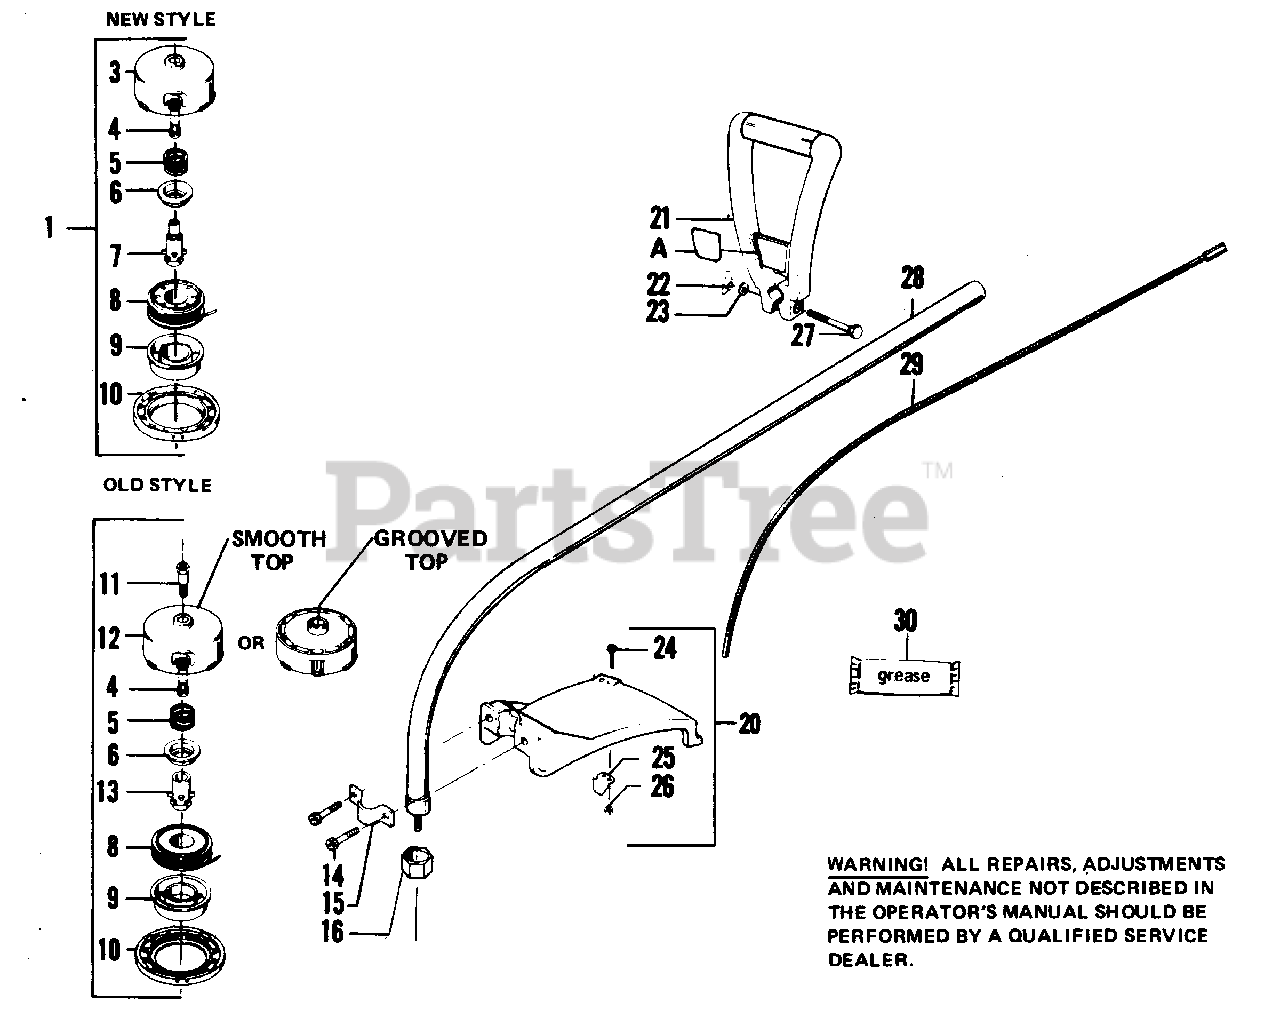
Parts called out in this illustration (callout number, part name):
1	Cutting Head Ass'y - New Style (Inc.3-10)
3	Hub w/Line Saver - New Style
4	Line Saver
5	Spring
6	Adaptor - Spring
7	Drive Gear - New Style
8	Spool w/Line
9	Release Button
11	Bolt - Drive Adaptor - Old Style
12	Hub w/Line Saver - Old Style - See Service Ref. 4
13	Drive Gear - Old Style
15	Bracket - Shield
16	Dust Cup
21	Assist Handle
22	Wing Nut - #1/4 - 20
23	Washer - #1/4 Flat
24	Screw - Line Limiter (#10 - 24 x 1")
25	Limiter - Line
26	Nut - Line Limiter
27	Hex Bolt - #1/4 - 20 x 2-1/4"
28	Drive Shaft Ass'y (Inc.16)
29	Fl??ble Shaft Ass'y
30	Flex Shaft Lube (Optional)
A	Decal - "D" Handle Warning
